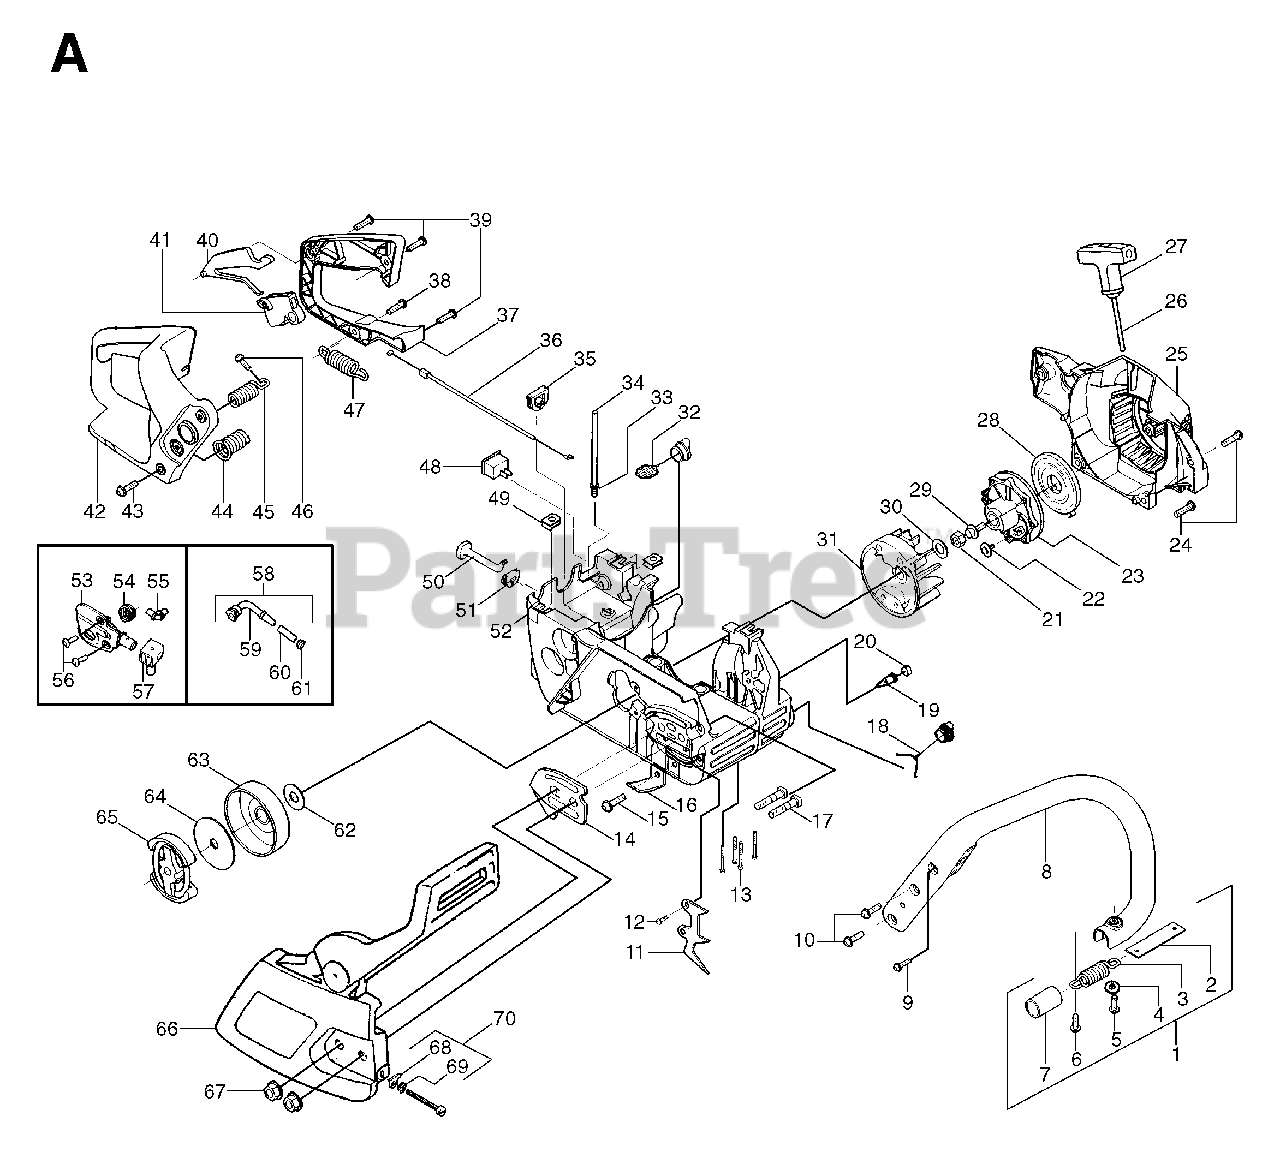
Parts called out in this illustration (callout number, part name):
1	ASSY-ISOLATOR
2	STRAP
3	SPRING
8	HANDLE
9	SCREW
11	SPIKE 36/41
12	SCREW-10-14 X 13/16 (PL
16	CHAIN CATCHER 36/41
17	BOLT
18	OIL TANK CAP
19	VALVE-CHECK (DUCKBILL)
20	BRONZE PLUG
21	NUT-FLYWHEEL
23	STARTER PULLEY
24	SCREW,STRTR CVR 36/41
25	STARTER HOUSING
27	HANDLE
30	WASHER-FLYWHEEL
31	FLYWHEEL ASS'Y
32	TANK CAP
33	FUEL LINE FITTING
34	LINE KIT
36	THROTTLE WIRE
38	SCREW-10-14 X 13/16 (PL
39	SCREW,FRONT HBAR 36/41
40	THROTTLE LOCK
41	THROTTLE TRIGGER
43	SCREW
44	SPRING
45	SPRING
47	SPRING
52	CRANKCASE
54	WORM GEAR
57	SEALING
59	PICK-UP OILER
60	FILTER
61	PLUG
62	DUST COVER 36/41
63	CLUTCH DRUM ASSY
64	FRICTION DISC,CLUTCH 36/41
65	CLUTCH ASSEMBLY
66	COVER
68	ADJUST PIN,BAR 36/41
